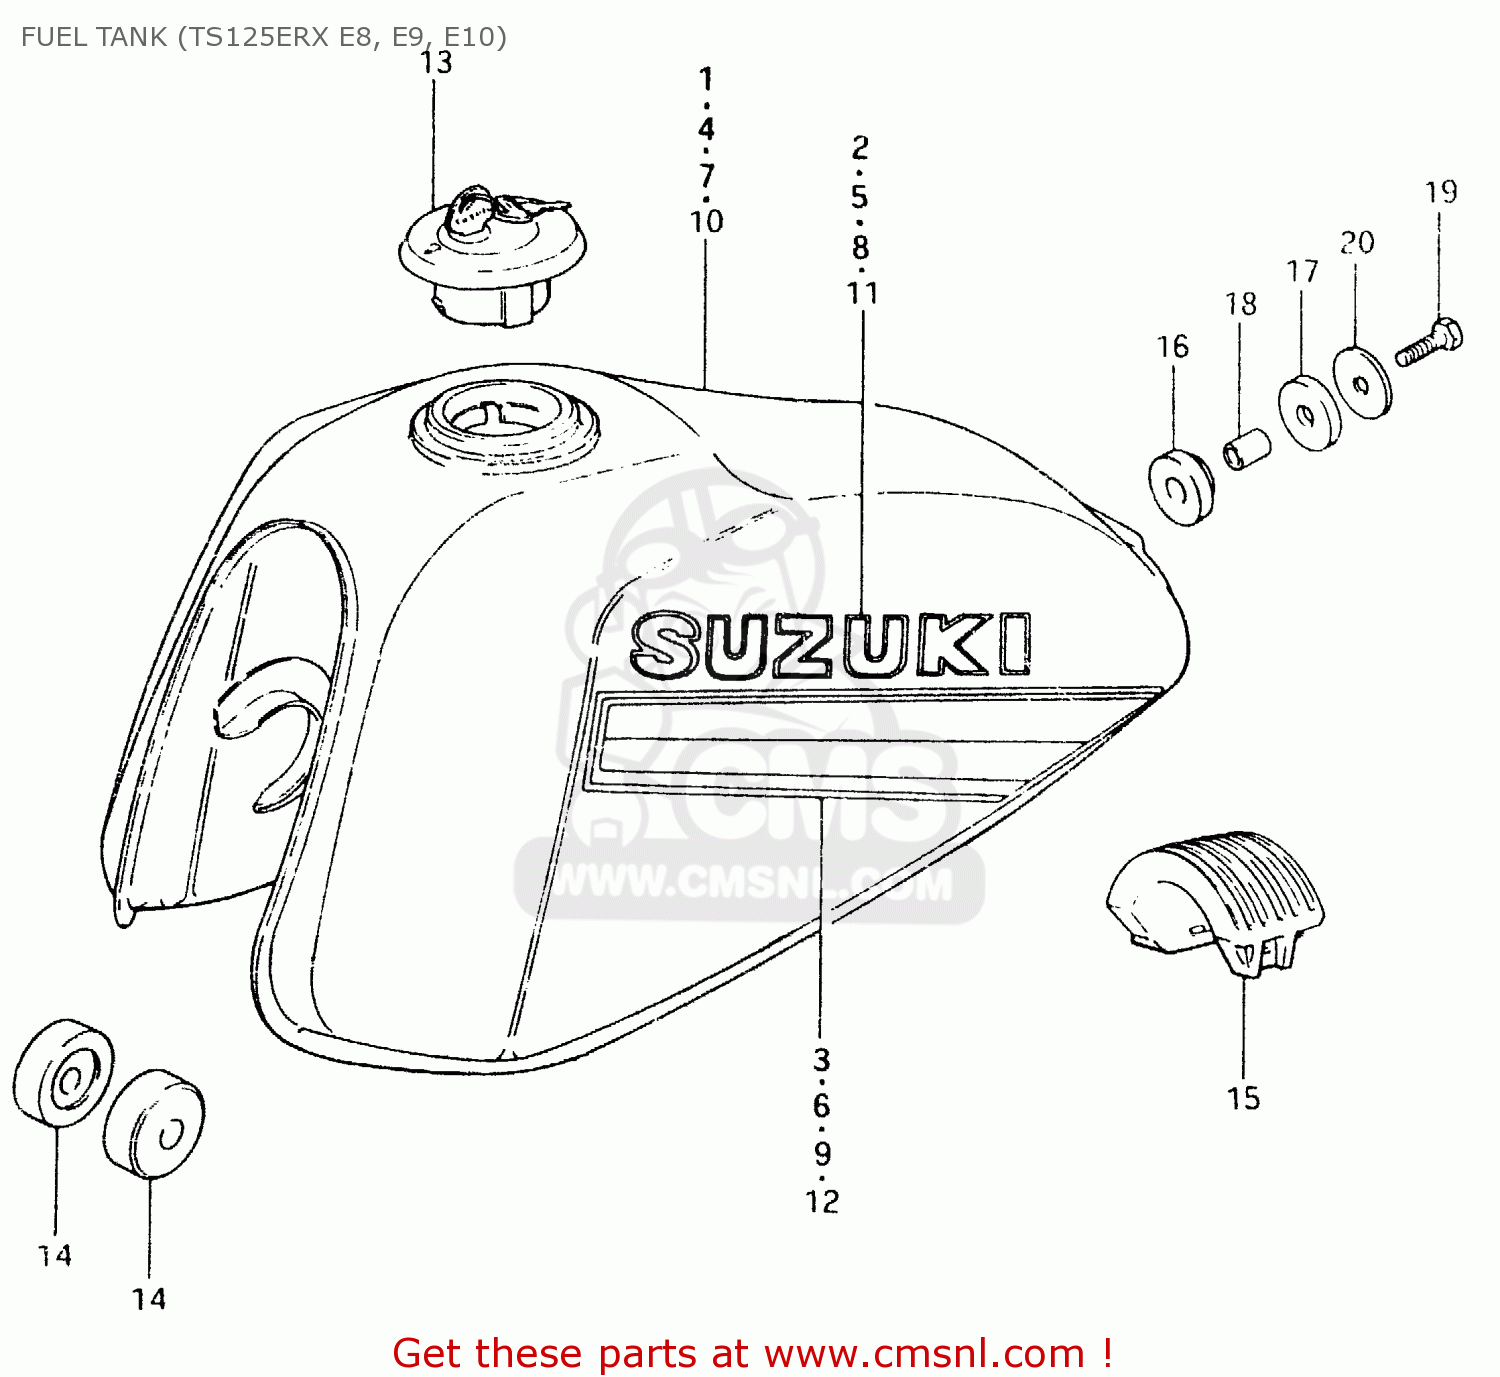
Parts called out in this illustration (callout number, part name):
1	TANK, FUEL (BLACK)
2	EMBLEM
3	TAPE SET
4	TANK, FUEL (YELLOW)
5	EMBLEM(BLACK)
6	TAPE SET
7	TANK, FUEL (RED)
8	EMBLEM
9	TAPE SET
10	TANK, FUEL (WHITE)
11	EMBLEM(BLACK)
12	TAPE SET
13	CAP SET,FUEL TANK
14	CUSHION
15	CUSHION,FUEL TANK
16	CUSHION
17	CUSHION
18	SPACER(8.5X12X19)
19	BOLT (8X30)
20	WASHER (8.5X29X1.6)
